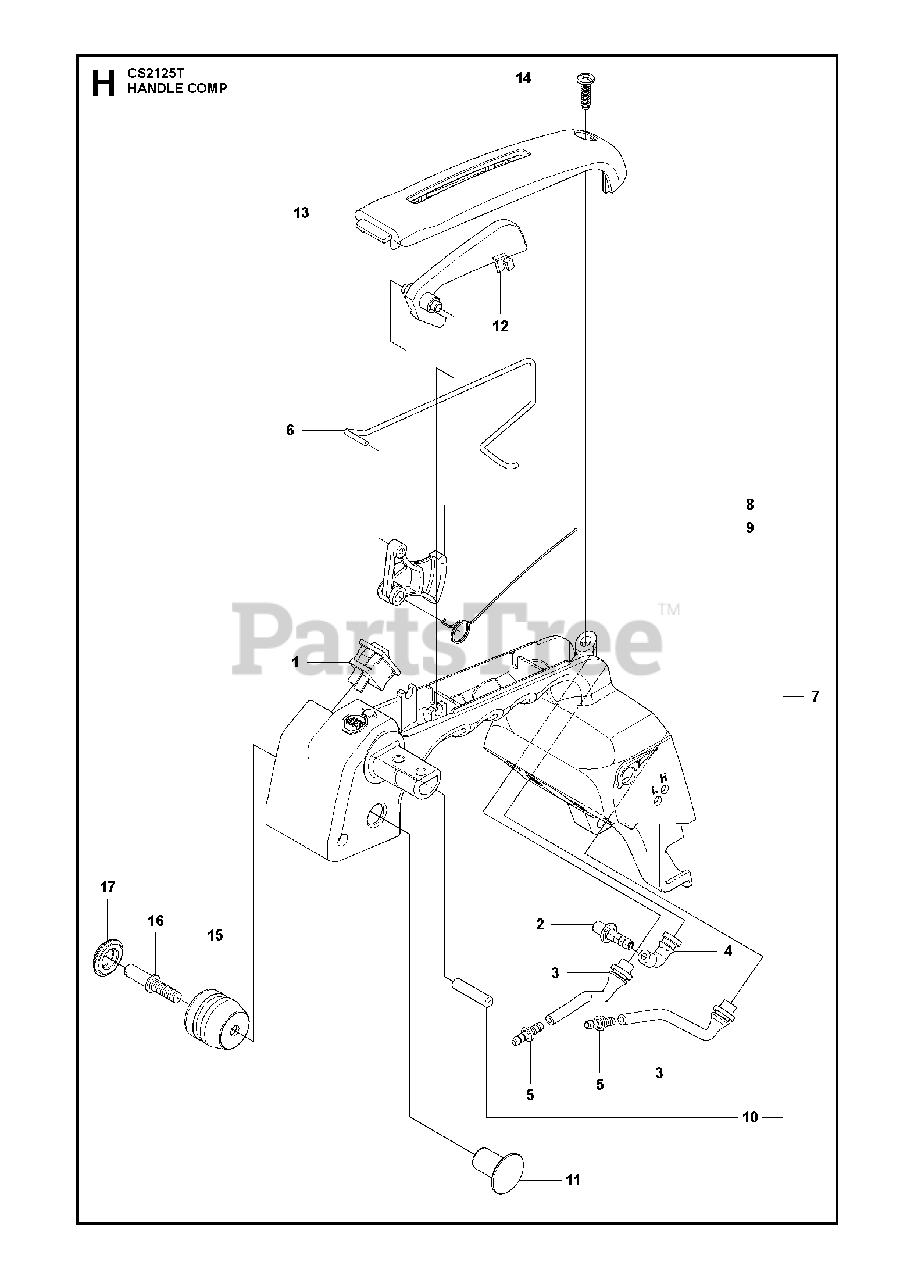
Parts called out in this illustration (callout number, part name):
1	SWITCH
2	ELBOW
5	JOINT
9	SPRING
16	BOLT
